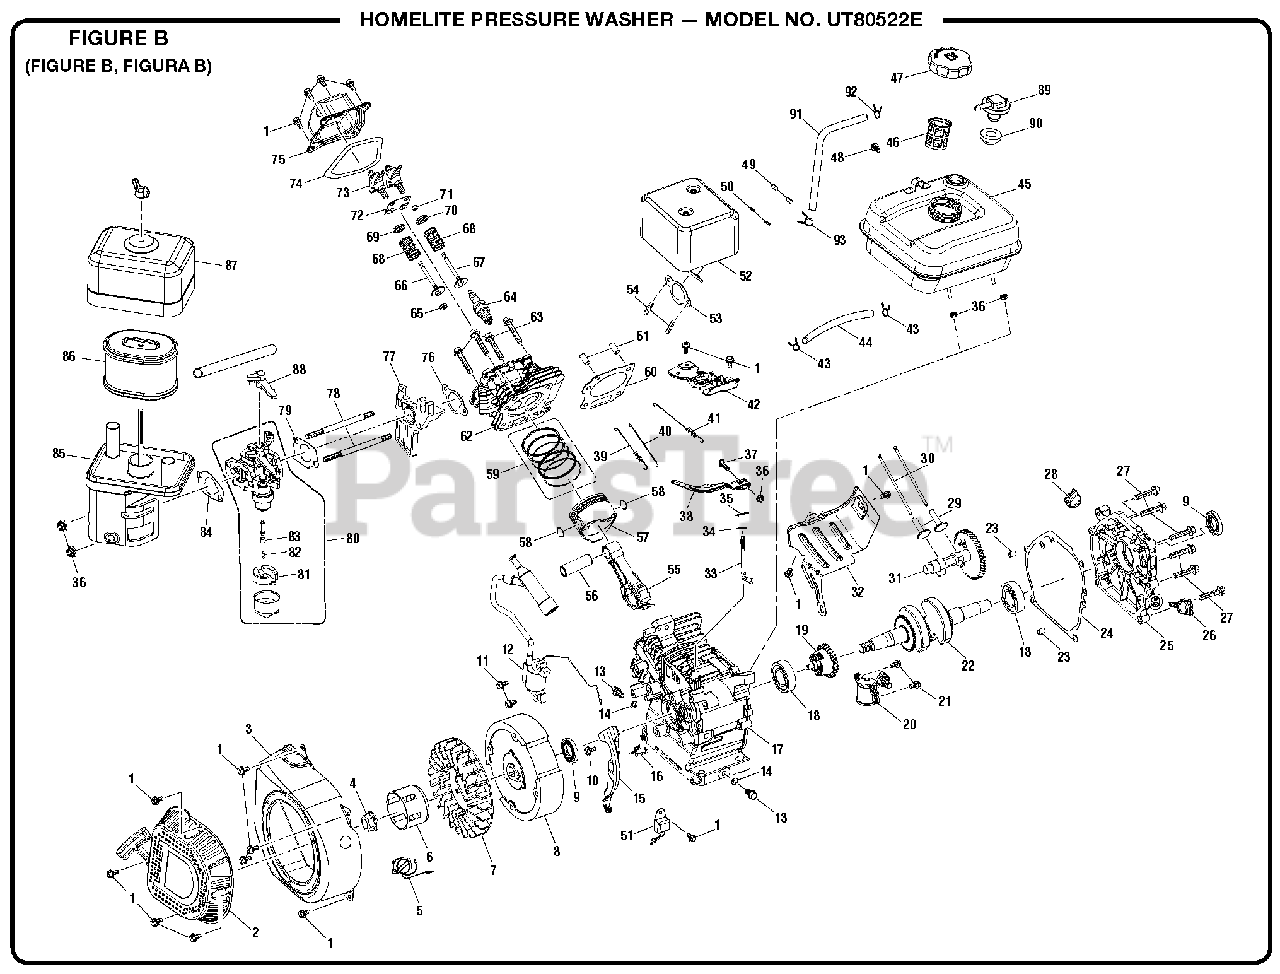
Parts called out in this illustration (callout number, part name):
2	Recoil Starter Assembly
5	Switch Assembly
6	Starter Pulley
8	Flywheel Assembly
12	Ignition Coil Assembly
13	Drain Plug Bolt
15	Lower Shield
17	Crankcase Assembly
18	Ball Bearing
19	Governor Gear Assembly
20	Engine Oil Sensor
22	Crankshaft Assembly
24	Crankcase Gasket
25	Crankcase Cover Assembly
29	Valve Lifter
31	Camshaft Assembly
33	Governor Arm
38	Governor Support Assembly
39	Throttle Valve Return Spring
40	Governor Rod
41	Governor Spring
42	Upper Shroud Assembly
43	Fuel Line Clip
45	Fuel Tank Assembly
46	Fuel Filter
50	Spring Washer
51	Oil Protector
52	Muffler Assembly
53	Exhaust Outlet Gasket
55	Connecting Rod Assembly
58	Piston Pin Clip
59	Piston Rings
60	Cylinder Head Gasket
62	Cylinder Head
66	Intake Valve
67	Exhaust Valve
68	Valve Spring
69	Valve Spring Seat
70	Exhaust Valve Retainer
71	Valve Rotator
72	Guide Plate Assembly
73	Rocker Assembly
74	Cylinder Head Gasket
75	Cylinder Head Cover Assembly
76	Carburetor Insulator Gasket
77	Carburetor Insulator Plate
79	Carburetor Gasket
80	Carburetor Assembly
84	Air Cleaner Gasket
85	Air Cleaner Base
86	Air Cleaner Element
87	Air Cleaner Case Cover
88	Choke Lever
89	Fuel Tank Vapor Vent
92	Fuel Line Clip
93	Fuel Line Clip
